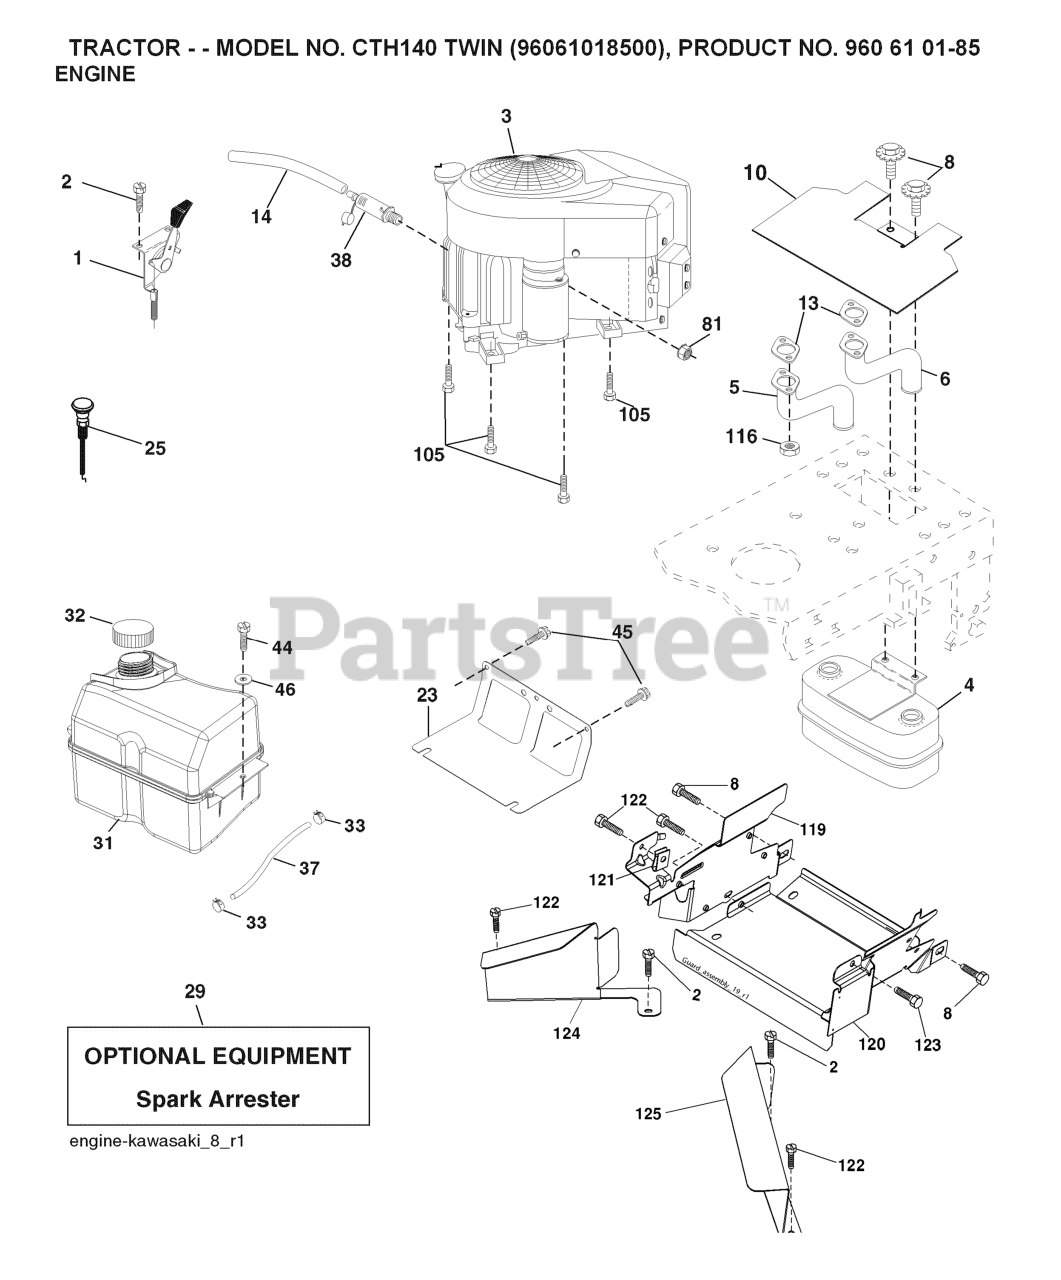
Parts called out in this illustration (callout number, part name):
1	CONTROL.THROTTLE.COBRA.BLACK
2	SCREW
4	MUFFLER.TWIN.CYL.LOW.TONE
5	EXHAUST TUBE LH KAWI
6	EXHAUST TUBE RH KAWI
8	BOLT.5/16-18UNCX3/4 W/SEMS.BLK
10	RP SHIELD HEAT MUFFLER
14	TUBE, DRAIN OIL ASM.
23	SHIELD.BROWNING.DBR.GUARD
25	CONTROL.CHOKE.ERGO.PUSH-IN.BLA
29	KIT.SPARK ARRESTOR 794945 B&S
31	RP TANK FUEL FRT 1.5 GAL
32	FUEL CAP
33	HOSE CLAMP
37	LINE.FUEL.20
44	SCREW HEXWSHR 1/4-20X3/4
45	SCREW, 3/8-16X3/4
81	NUT
105	SCREW 3/8-16X1
116	NUT.HEX.FLANGE.TOPLOCK
119	LENKRAD
120	GUARD 532199767
122	SCREW.1/4-20X5/8
123	SCREW, 5/16-18 X 1/2
126	SCREW
